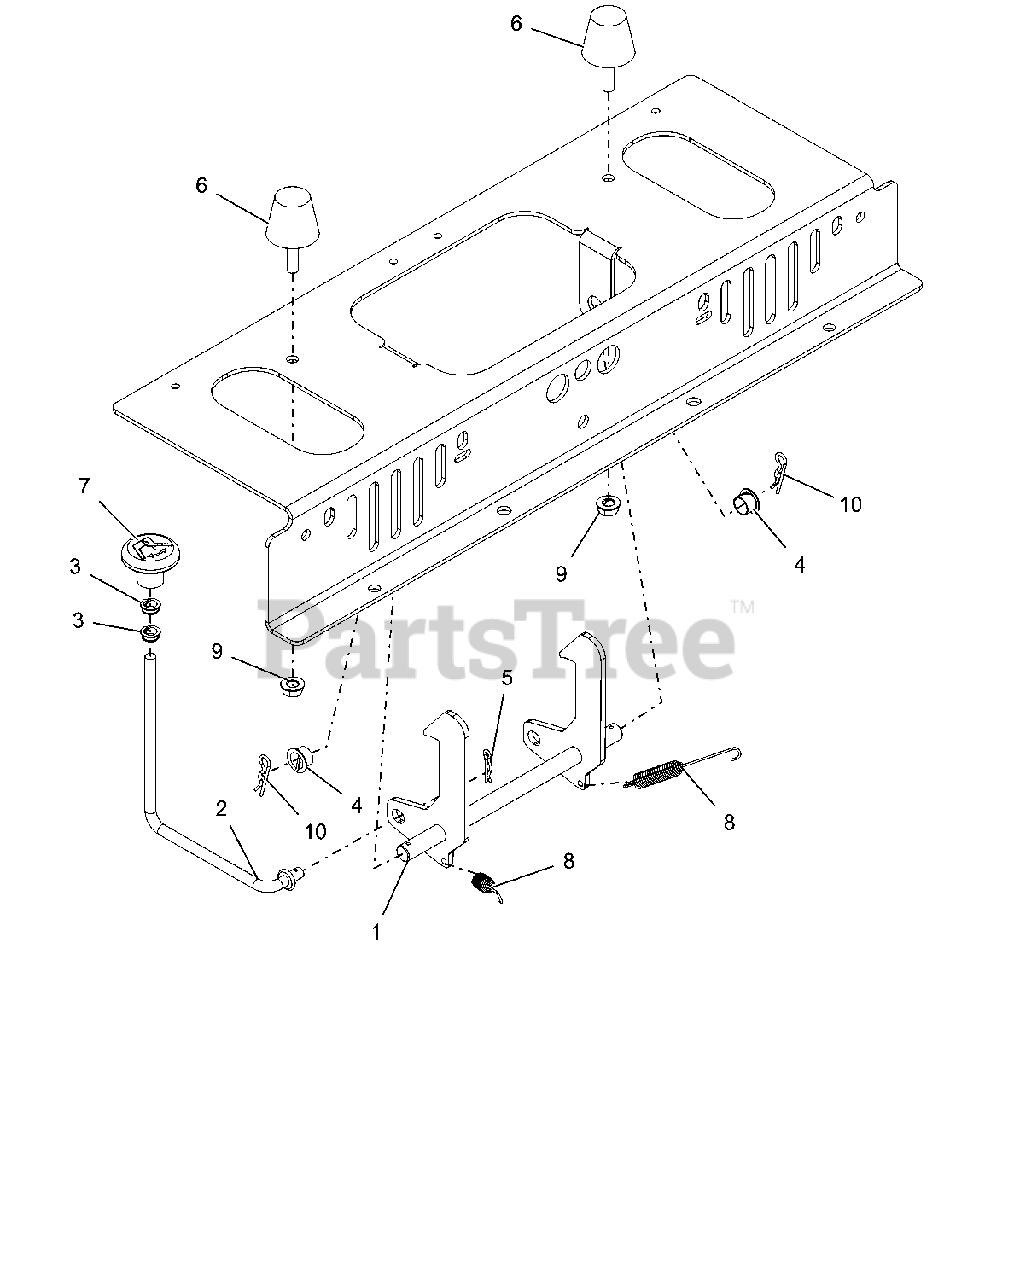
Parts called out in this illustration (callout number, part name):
1	WMT, SEAT LATCH (BLACK)
2	LINKAGE, SEAT RELEASE
3	BSHG, POLYLINER-.38 SNAPIN
4	BUSHING, POLYLINER - .50 SPLIT
5	PIN-HAIR, ENDRIES #25 YWZC
6	BUMPER, STUD MOUNTED CONE SHAPED
7	KNOB, PUSH/PULL
8	SPRG, EXTENSION
9	@NUT-SPNLK-FLG .312-18 YWZC
10	PIN-HAIR INT .08X.38X1.42 YWZC
